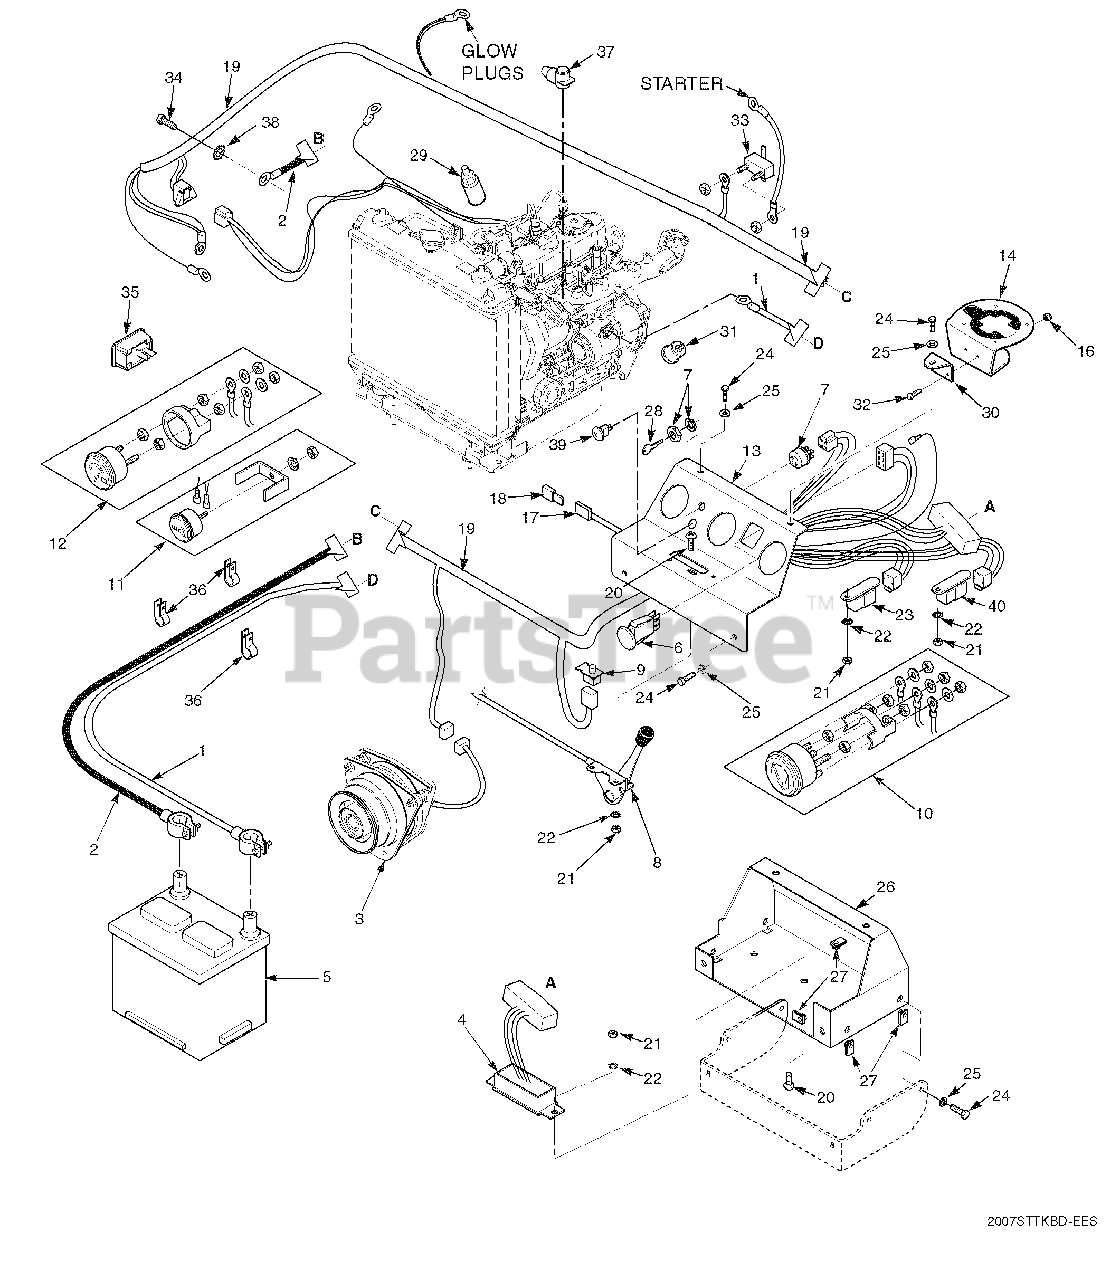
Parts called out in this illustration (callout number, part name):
1	Cable, Positive Battery
2	Cable, Negative Battery
3	Clutch, Electric PTO
4	Module, Interlock
5	Battery
6	Switch, PTO
7	Switch, Key
8	Cable, Control
9	Switch, Seat
10	Gauge, Water Temperature
11	Gauge, Oil Pressure
12	Gauge, Voltmeter
13	Panel, Instrument Panel
14	Cup Holder Accessory
15	Screw, #10-32 x 1.5” Phillips
16	Nut, #10-32 Elastic Stop
17	Fuse Holder w/ 20 Amp Fuse
18	Fuse, 20 Amp
19	Harness, Wiring
20	Screw, #10-32 x .5” Phillips
21	Nut, Hex #10-32
22	Lock Washer #10
23	Relay
24	Bolt, Hex Head 1/4-20 x .75”
25	Lock Washer 1/4”
26	Base, Instrument Panel
27	U-Nut, 1/4-20
28	Key & Ring Assembly
29	Sender Unit, Water Temperature
30	Cup Holder Mounting Bracket
31	Sender Unit, Oil Pressure
32	Bolt, Hex Head 1/4-20 x 3/4”
33	50 Amp Breaker
34	Bolt, Hex Head M8-1.25 x 14
35	Hour Meter
36	Clamp, Cable .5” ID
37	Boot, Positive Battery Terminal
38	Washer, Star
39	Indicator Light, Glow Plugs
40	Relay, 40 Amp
